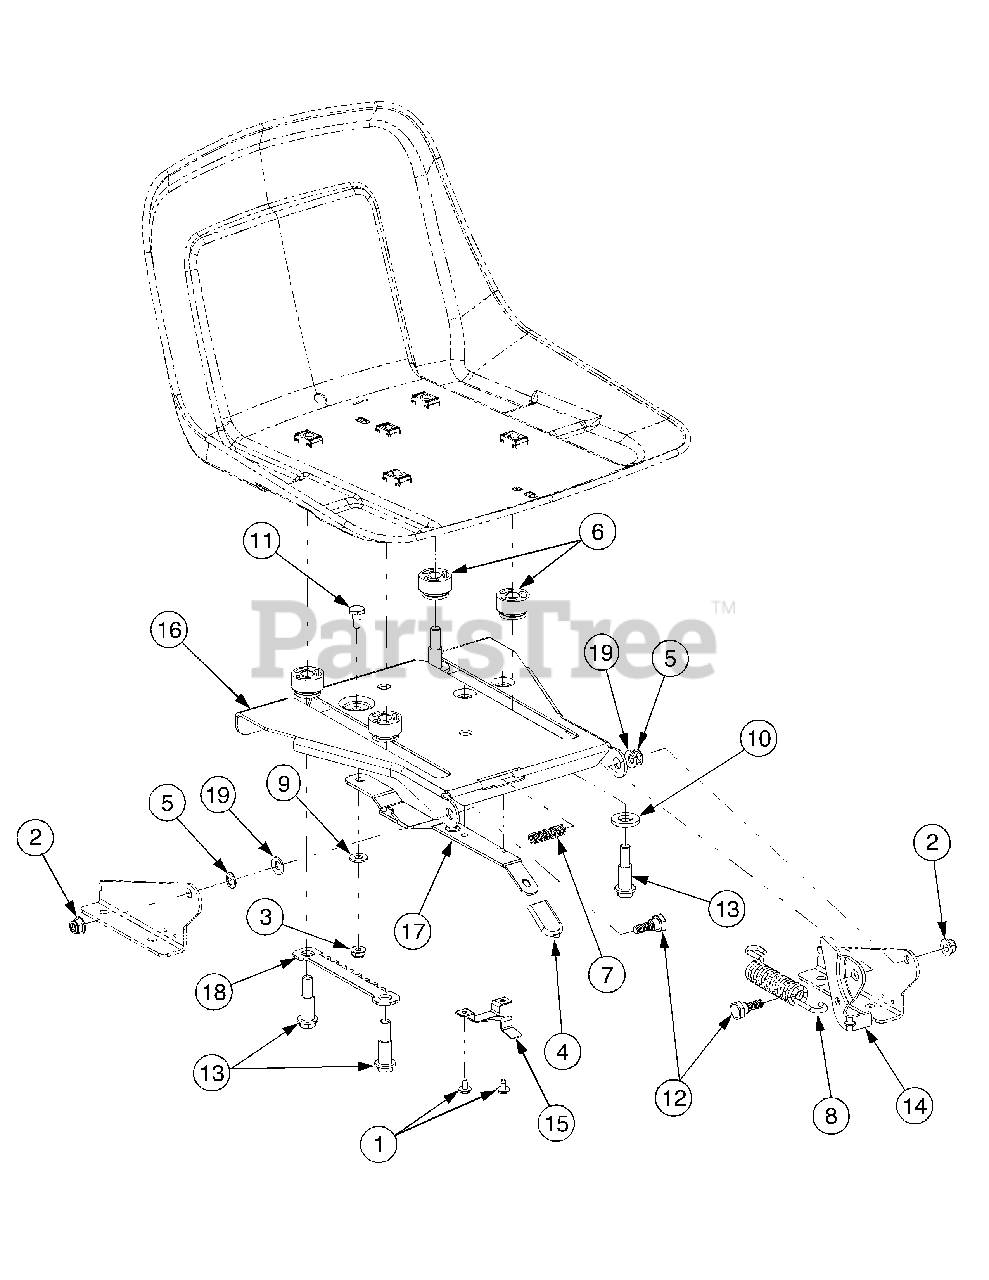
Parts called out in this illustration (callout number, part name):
1	Screw, Hx. Wash. Hd. Tapp #10-16 x .375
2	Nut, Hx Insert Flange Lck, 5/16-18 GrF
3	Nut, Hx Insert Flnge Lck, 1/4-20 GrF
4	Grip, Seat Adjustment
5	Nut, Speed, .3125
6	Spacer, Seat Adjustment
7	Spring, Compression, .41 x 1.5
8	Spring, Extension, .84 Dia. x 4.6
9	Washer, Flat, .344 x .62 x .033
10	Washer, Flat, .531 x 1.062 x .134 HT
11	Screw, Shoulder, .34 x .285:1/4-20
12	Screw, Shoulder, .437 x .268:5/16-18
13	Screw, Shoulder, .5 x .925:3/8-16 ..
14	Bracket, Seat Lift
15	Stop, Seat Adjustment
18	Index Bracket, Seat Adjustment
19	Washer, Belleville, .34 x .872 x .06
